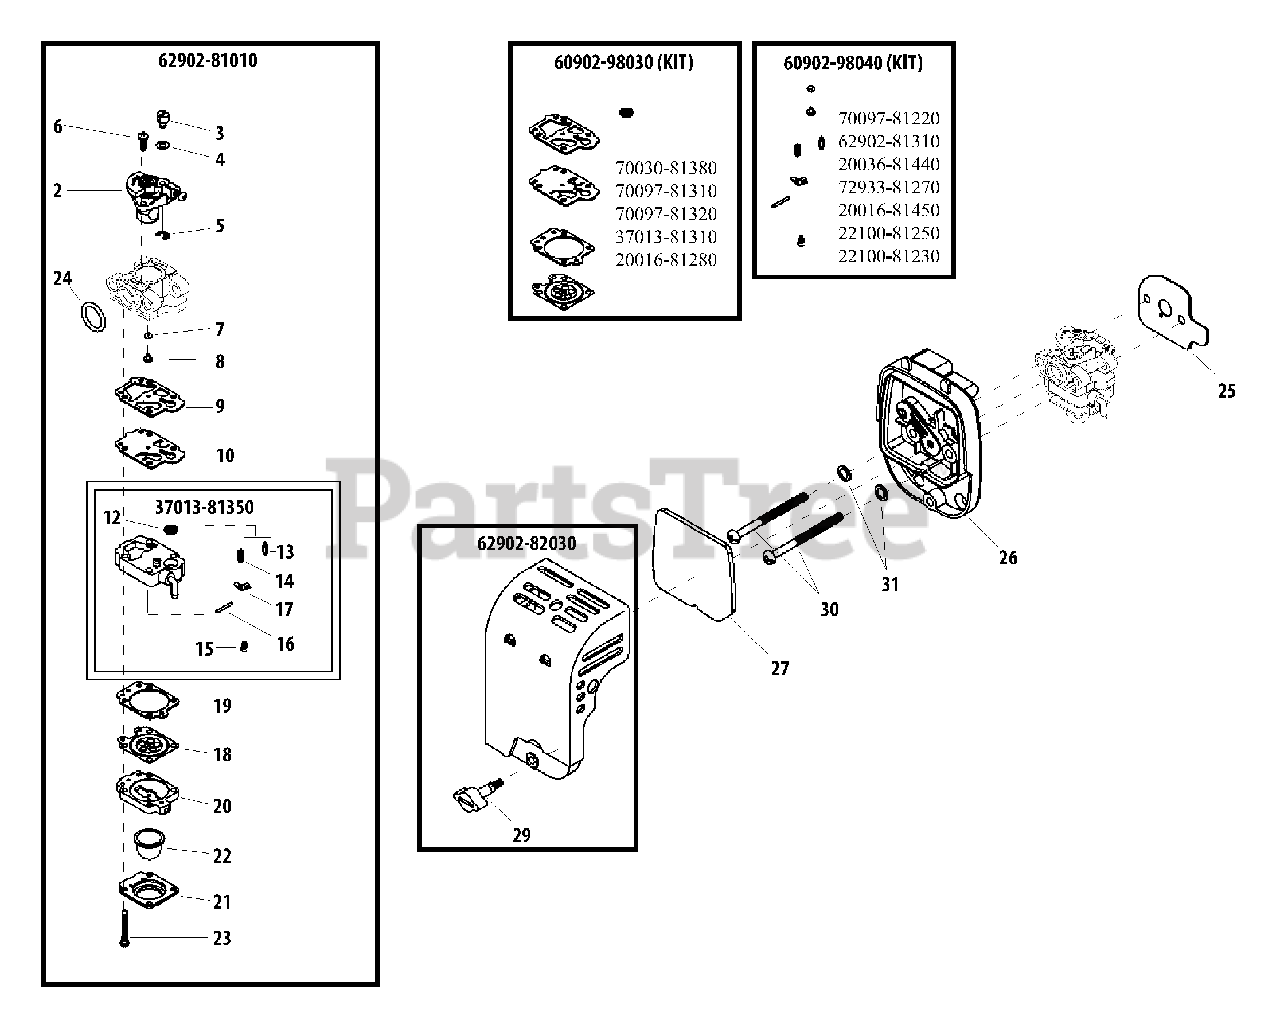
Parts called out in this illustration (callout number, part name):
2	THROTTLE VALVE ASSY
3	SWIVEL
4	WASHER
5	RING, RETAINING
6	SCREW
7	O-RING
8	JET, MAIN
9	GASKET, PUMP
10	DIAPHRAGM, PUMP
12	STRAINER
13	VALVE, INLET NEEDLE
14	SPRING, METERING LEVER
15	SCREW, METERING LEVER PIN
16	PIN, METERING LEVER
17	LEVER, METERING
18	DIAPHRAGM, METERING
19	GASKET, METERING
20	BASE, PURGE
21	RETAINER, PURGE BULB
22	BULB, PURGE
23	SCREW, PUMP COVER
24	O-RING - 15
25	GASKET
26	CASE, AIR FILTER
27	FILTER, AIR
29	THUMBSCREW
30	SCREW - 5X60
31	WASHER - 5
37013-81350	PUMP BODY ASSY
60902-98030	DIAPHRAGM/GASKET KIT
60902-98040	INLET NEEDLE VALVE KIT
62902-81010	CARBURETOR
62902-82030	AIR FILTER COVER ASSY
